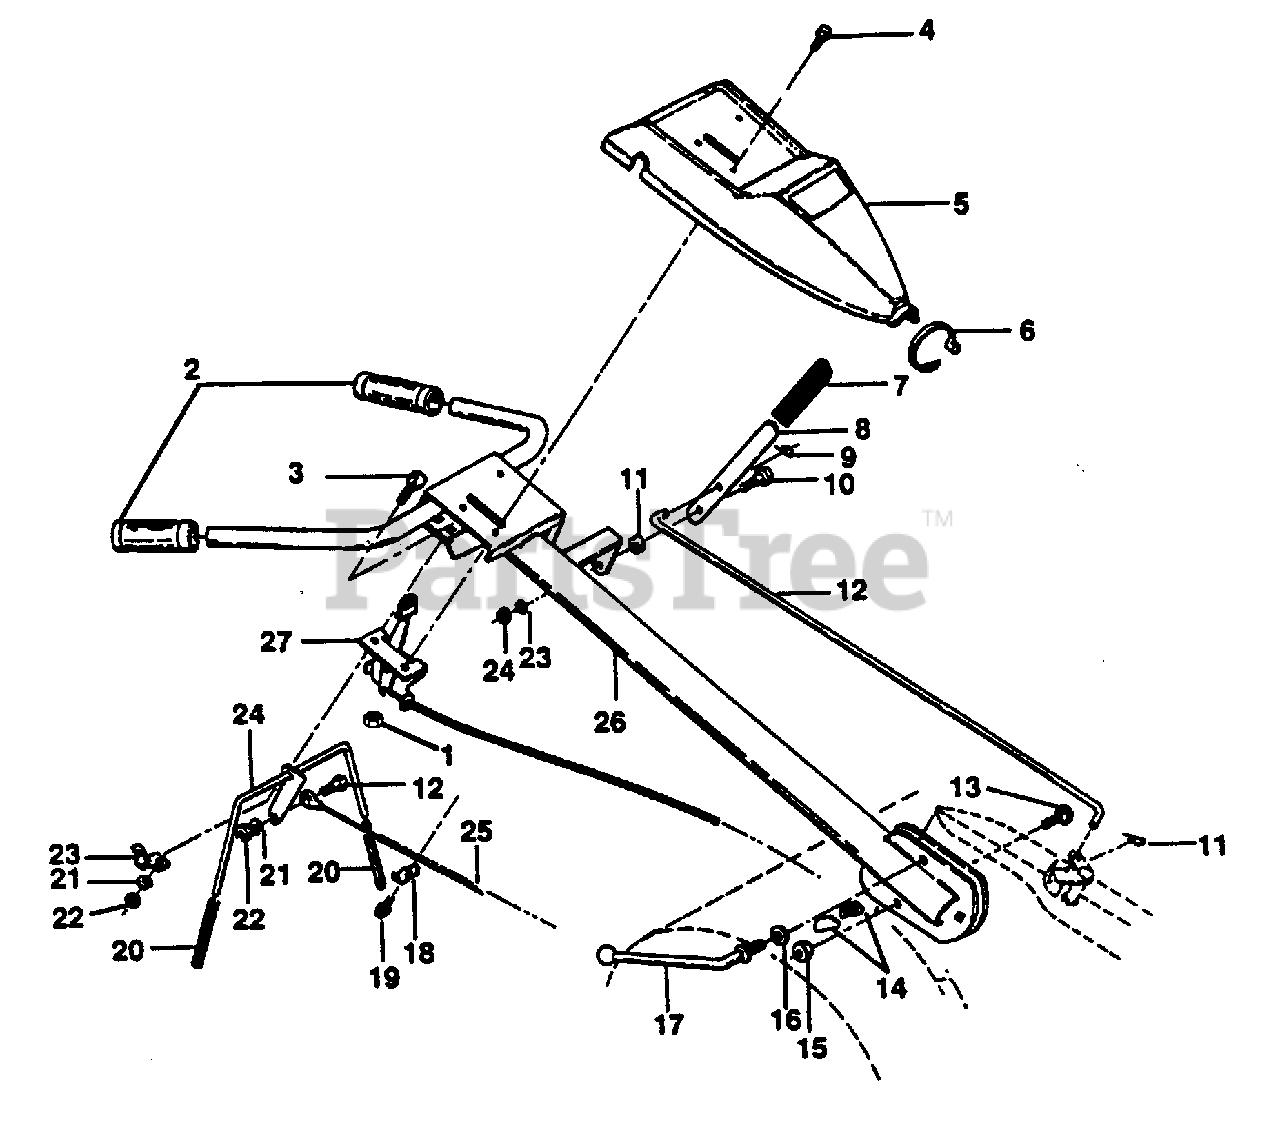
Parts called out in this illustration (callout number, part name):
1	Nut, Keps #10-24 UNC (AYP part number)
2	Grip, Handle (AYP part number)
3	Bolt, Carriage 1/4-20 (AYP part number)
4	Screw, Truss Hd. #10-24 UNC x 1/2 (AYP part number)
5	Panel, Control (AYP part number)
6	Tie, Cable (AYP part number)
7	Grip, Handle (AYP part number)
8	Handle, Shift (AYP part number)
9	Clip, Hairpin (AYP part number)
10	Bolt, Shoulder (AYP part number)
11	Grommet, Rubber (AYP part number)
12	Rod, Shift (AYP part number)
13	Bolt, Carriage 3/8-16 x 1 Gr. 5 (AYP part number)
14	Lock, Handle (AYP part number)
15	Nut 3/8-16 (AYP part number)
16	Washer 13/32 x 1 x 11 Ga. (AYP part number)
17	Lever, Lock, Handle (AYP part number)
18	Clip (AYP part number)
19	Screw, Hex, Washer Hd., Slotted # 10-24 x 1/2 (AYP part number)
20	Grip, Bar, Control (AYP part number)
21	Washer, Lock 1/4 (AYP part number)
22	Nut, Hex 1/4-20 (AYP part number)
23	Clamp, Bar, Control (AYP part number)
24	Assembly, Bar, Control (AYP part number)
25	Cable, Clutch (AYP part number)
26	Handle (AYP part number)
27	Control, Throttle (AYP part number)
